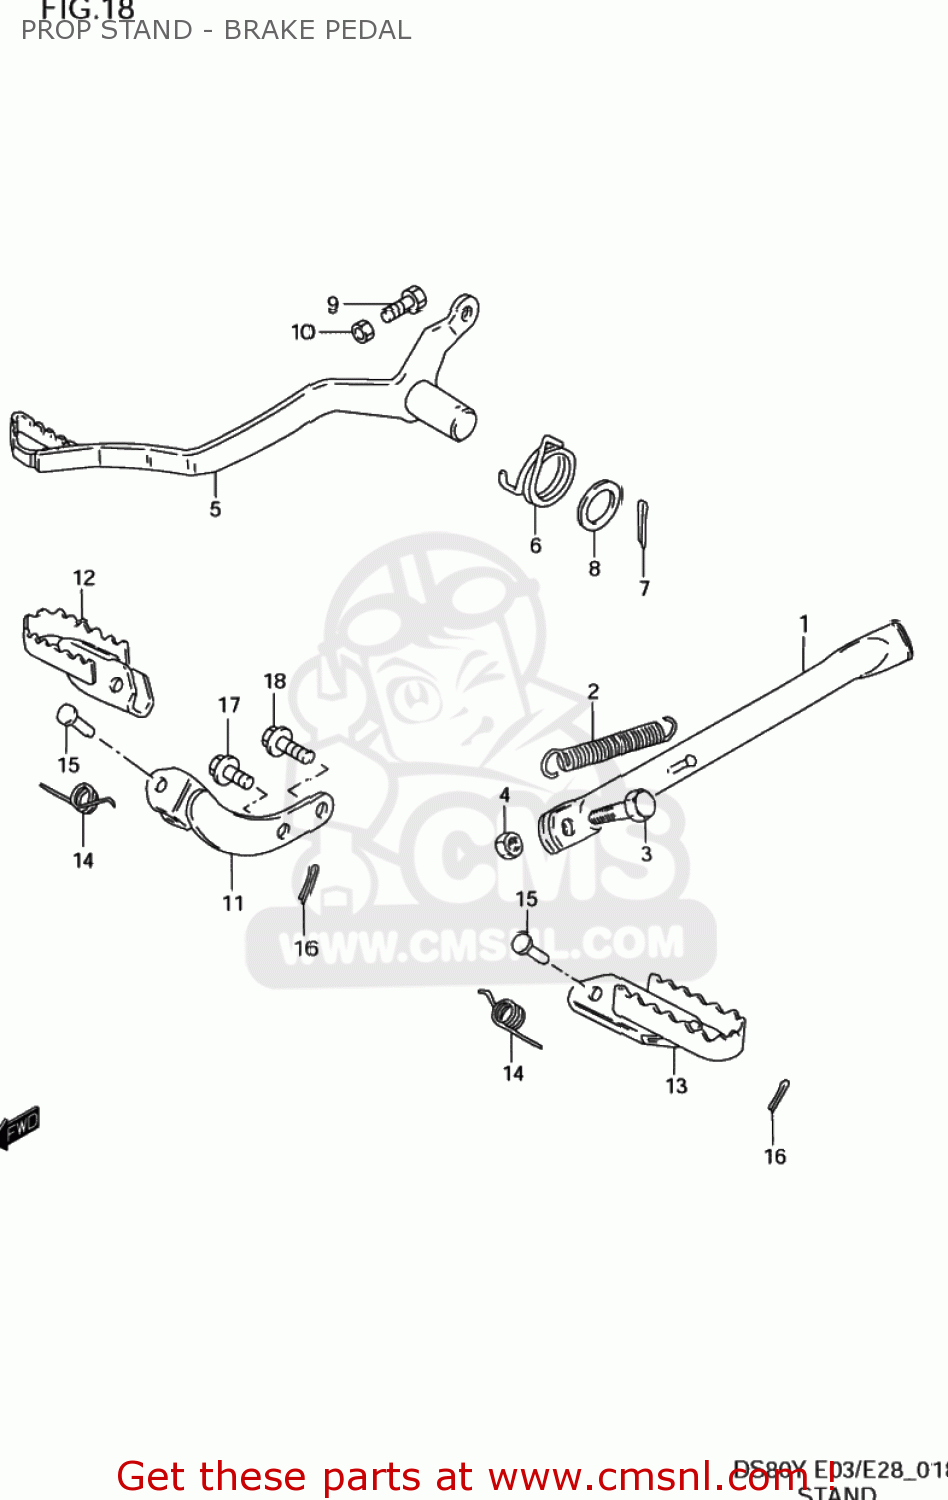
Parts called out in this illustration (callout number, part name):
1	STAND,SIDE
2	SPRING
3	BOLT(10X27)
4	NUT
5	PEDAL,BRAKE
6	SPRING
7	COTTER PIN
8	WASHER(15.5X26X2.3)
9	BOLT(6X23)
10	NUT 6MM
11	BAR,FRONT FOOTREST
12	FOOTREST,FR,R
13	FOOTREST,FR,L
14	SPRING
15	PIN
16	PIN
17	BOLT
18	BOLT(8X20)
